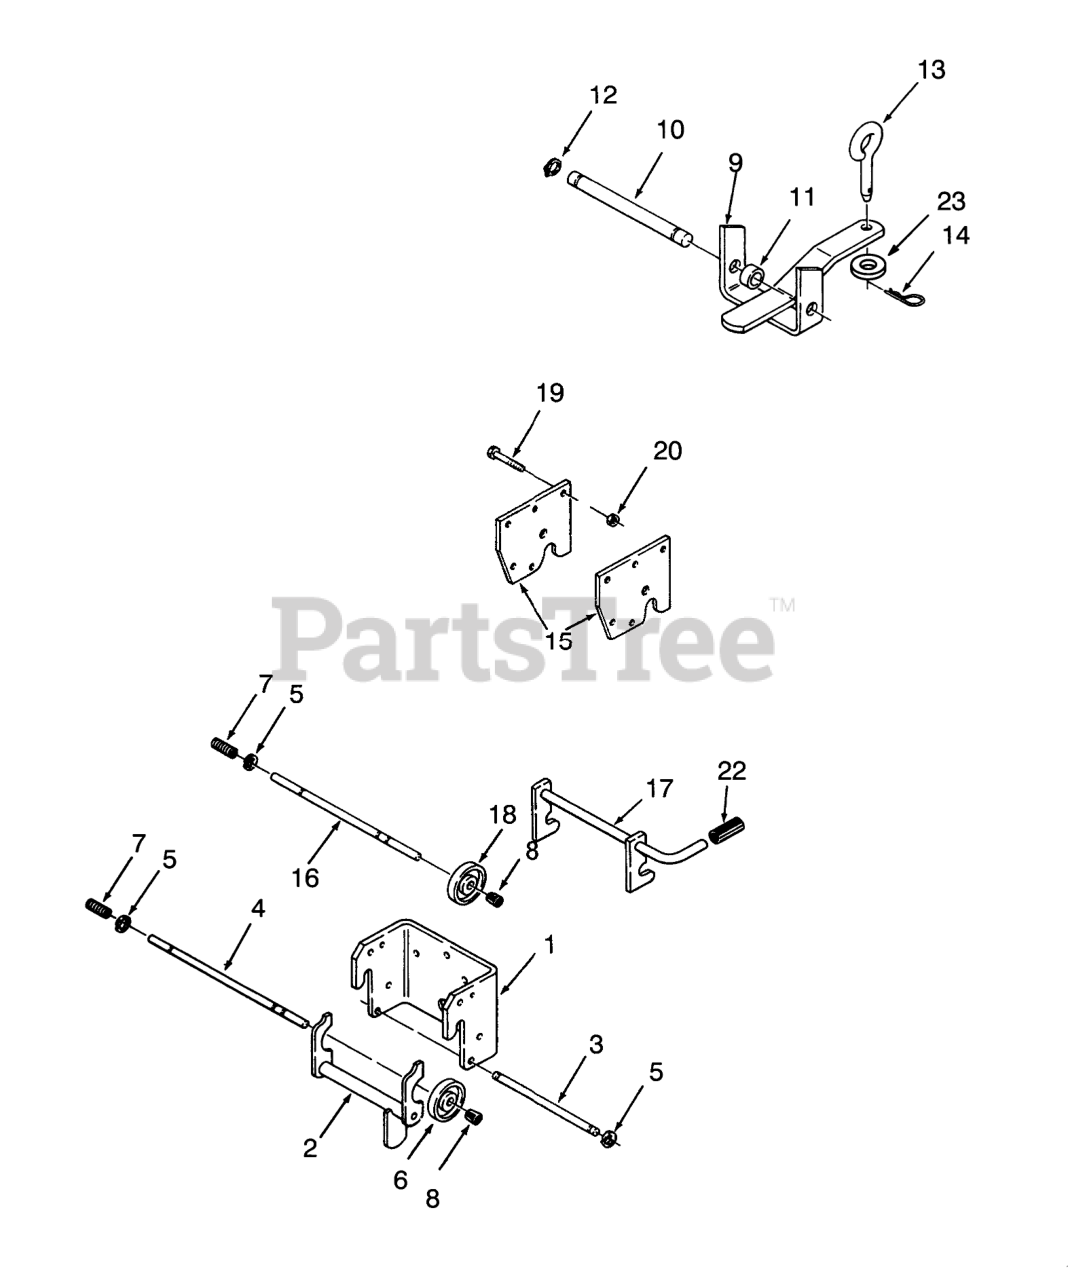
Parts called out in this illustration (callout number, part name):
1	Front Hitch
2	Assy-Latch
3	ROD-LATCH PIVOT
4	ROD-LOCK
5	RING-RETAINING
7	SPRING
8	CAP-ROD, PLUNGER
9	Hitch
10	PIN-STATIONARY HITCH
11	SPACER
12	E-RING
13	PIN-TOOL
14	PIN-HAIR
15	Hitch Plate
16	ROD-LOCK
17	MID HITCH ASM
19	SCREW-HH
22	GRIP
23	WASHER-FLAT
